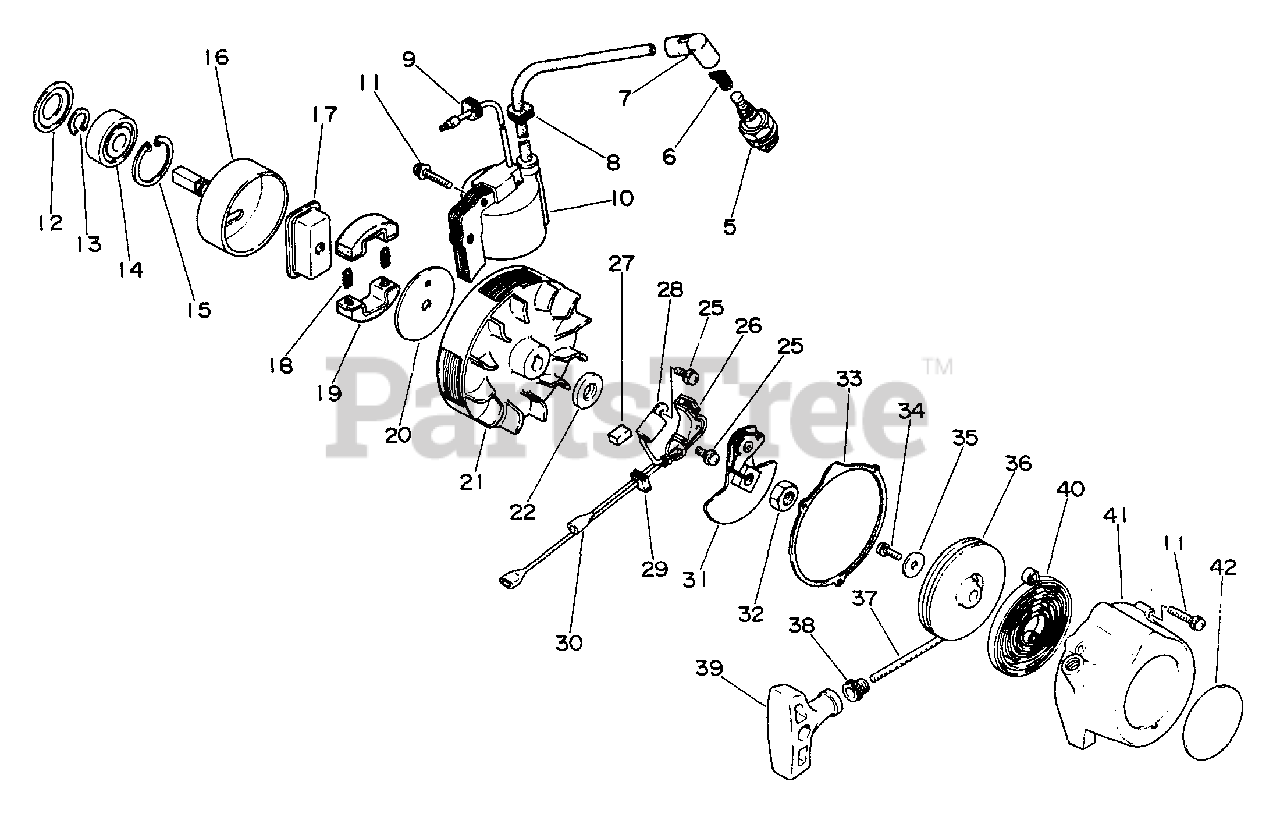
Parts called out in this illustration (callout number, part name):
5	SPARK PLUG -- CJ-8
6	TERMINAL, SPARK PLUG CAP
7	CAP, SPARK PLUG
10	COIL, IGNITION
11	SCREW - 4X20
12	RETAINER, PIPE
13	RING, RETAINING - 12
14	BEARING, BALL - 6201
15	RING, RETAINING - 32
16	DRUM, CLUTCH
17	HUB, CLUTCH
18	SPRING, CLUTCH
19	SHOE, CLUTCH
20	PLATE, CLUTCH
21	FLYWHEEL
25	SCREW - 4X10
26	CONTACT POINT SET
27	PAD, OIL
28	CONDENSER
30	LEAD - GROUND
31	STARTER PAWL ASSY
33	GASKET, STARTER
34	SCREW - 4X10
36	REEL, ROPE
37	ROPE, STARTER - 3X850
38	GUIDE, ROPE
39	GRIP, STARTER
40	SPRING, REWIND
41	CASE, STARTER
42	LABEL - ECHO
